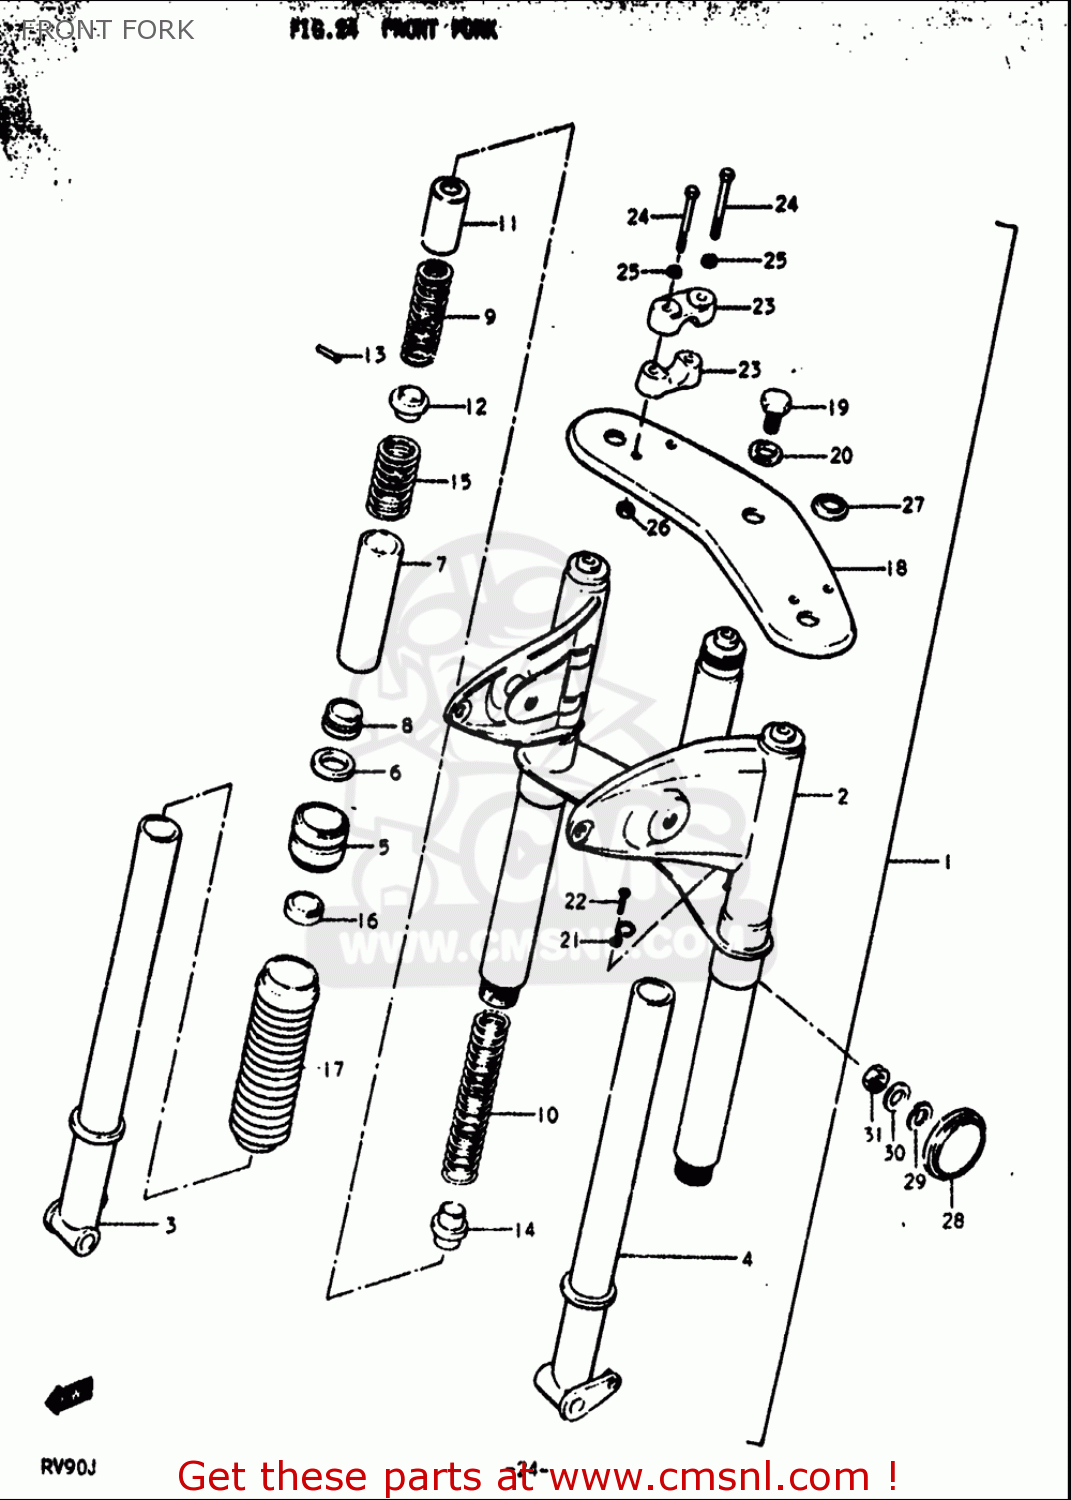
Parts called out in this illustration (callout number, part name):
13	PIN,SPRING(4.5X22)
16	CUSHION
21	CLIP
22	SCREW
23	HOLDER,HANDLEBAR
24	BOLT
25	WASHER,LOCK
26	NUT
27	WASHER
28	REFLEX REFLECTOR,RR
29	WASHER,LOCK
30	WASHER
31	NUT
